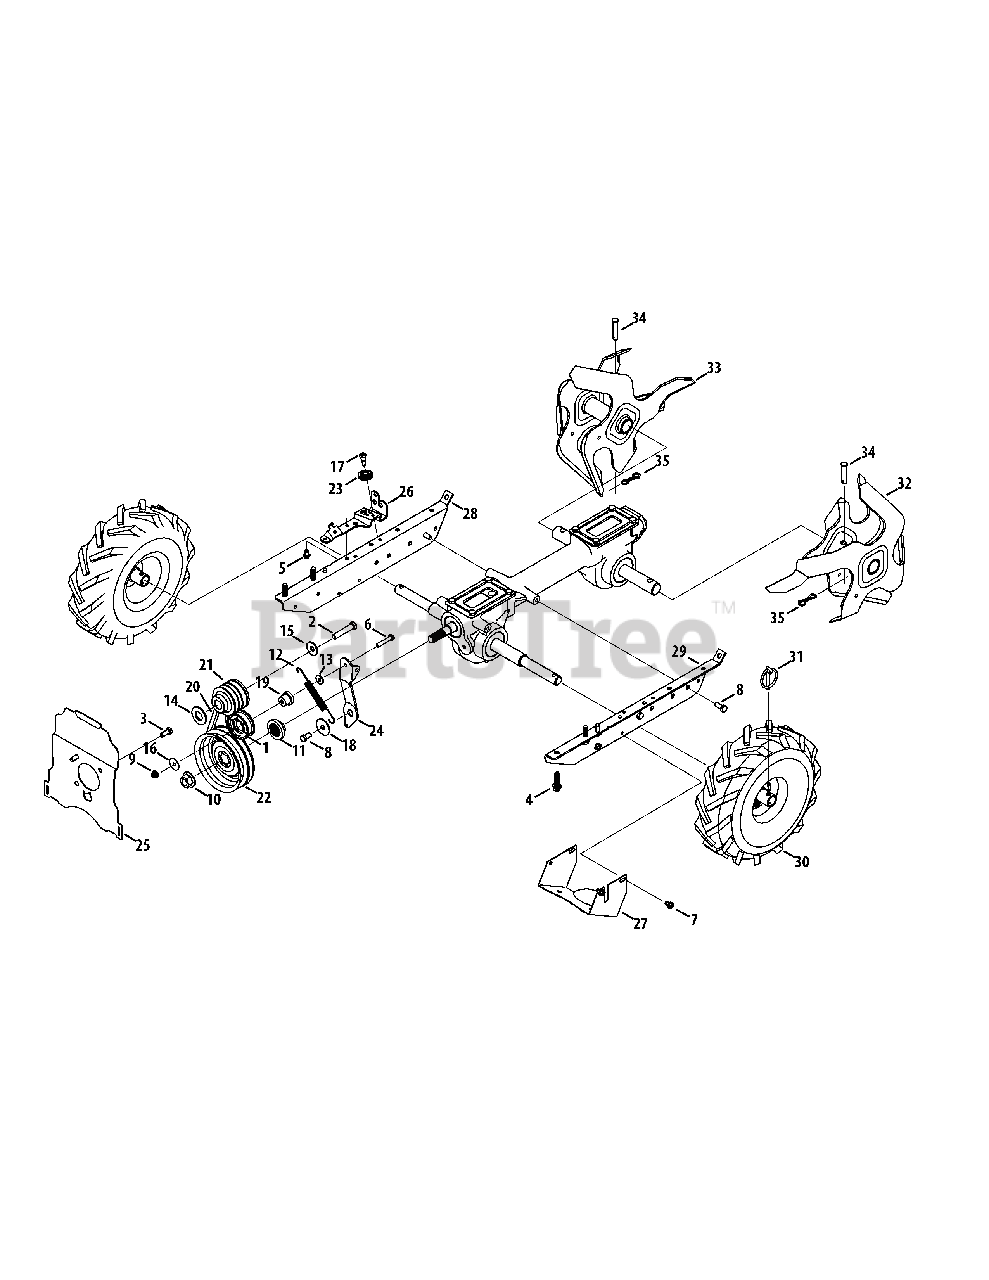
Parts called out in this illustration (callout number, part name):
1	Idler Pulley Assembly
2	Hex Head Screw, 3/8-24 x 2.00
3	Hex Head Screw, 5/16-24 x .625
4	Hex L-Washer TT-Tap, 3/8-16 x 1.25"
5	Self Tapping Screw, 1/4-20 x .500
6	Hex Head Screw, 1/4-20 x 1.50
7	Self Tapping Screw, 1/4-14 x .625
8	Hex Head Screw, 5/16-18 x .75, Patch
9	Nylon Hex Lock Nut, 1/4-20
10	Nut, 9/16-18, Flange Lock
11	Hub, 5/8 Spline
12	Extension Spring, .480 OD X 5.00 LG
13	Washer, .28 x .74 x .063
14	Washer, Flat, .760 x 1.50 x .120
15	Bell Washer, .396 x 1.140 x .095
16	Flat Washer, .265 x 1.0 x .030
17	Shoulder Screw, .342 x .335 1/4-28
18	Pivot Idler Spacer
19	Shoulder Spacer, .260 x .785 x .538
20	V-Belt, 4L x 25.375 Long
21	Engine Pulley
22	Transmission Pulley
23	Cable Roller
24	Idler Bracket, Forward
26	Pulley Bracket
27	Pulley Shield
28	Mounting Frame, RH
29	Mounting Frame, LH
30	Wheel Assembly, 11 x 4 x 4
30	Valve, Tubeless Air
30	Tire, 11 x 4 x 4
32	Tine Assembly, LH
33	Tine Assembly, RH
34	Clevis Pin, .375 x 1.75
35	Cotter Pin, Bow Tie
